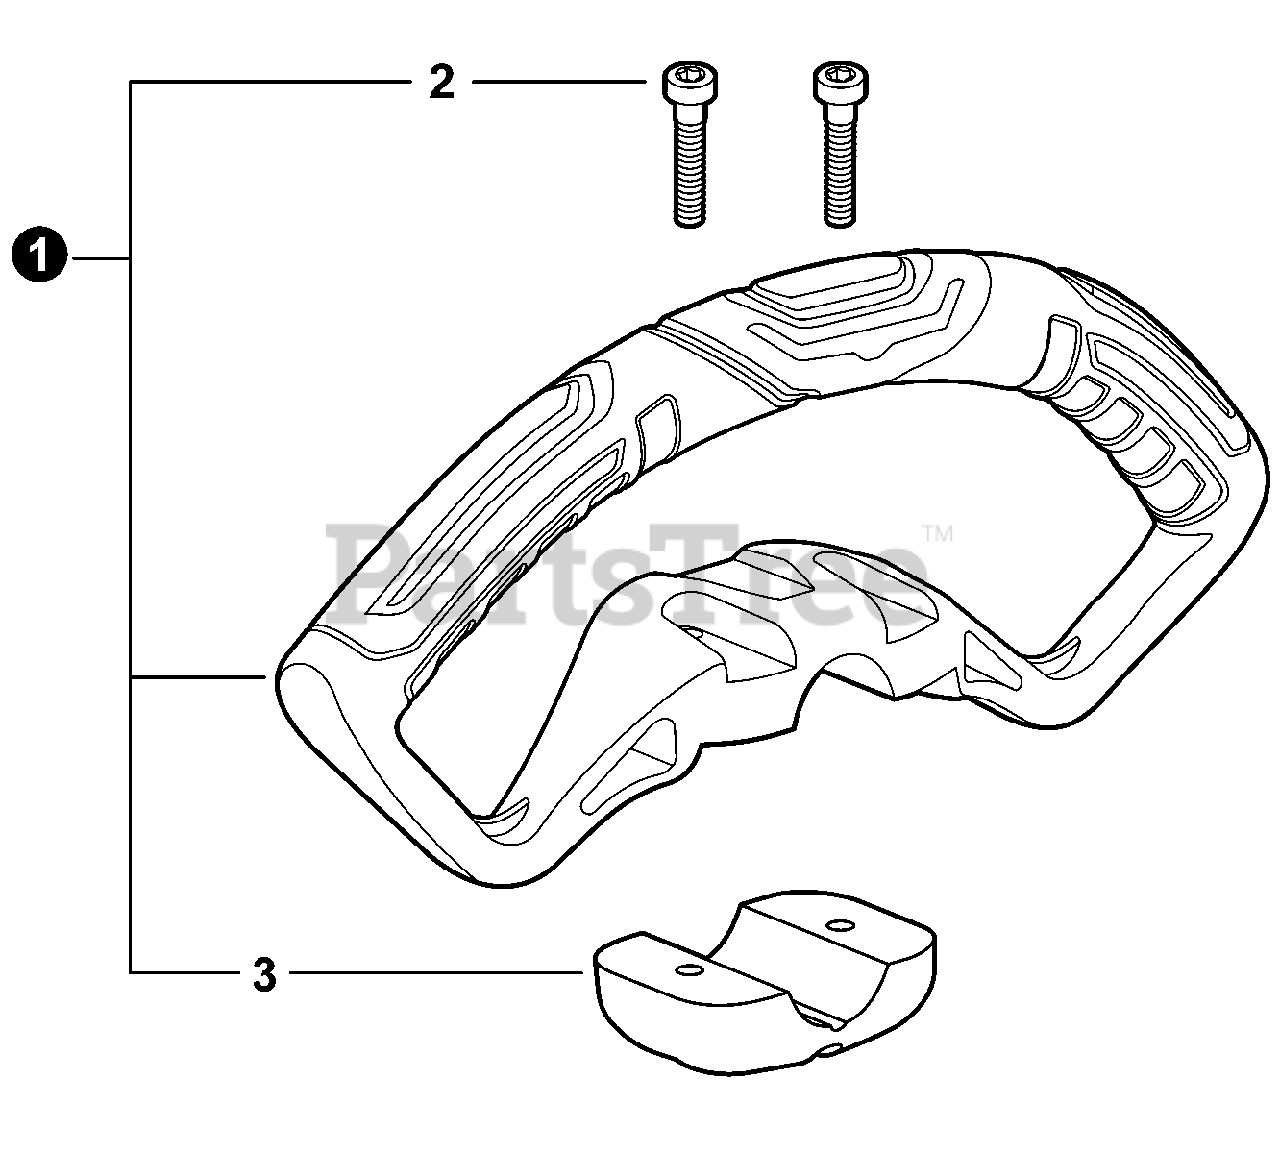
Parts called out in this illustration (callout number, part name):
1	HANDLE ASSY, SUPPORT
2	BOLT, TORX 5×30
3	BRACKET, HANDLE
